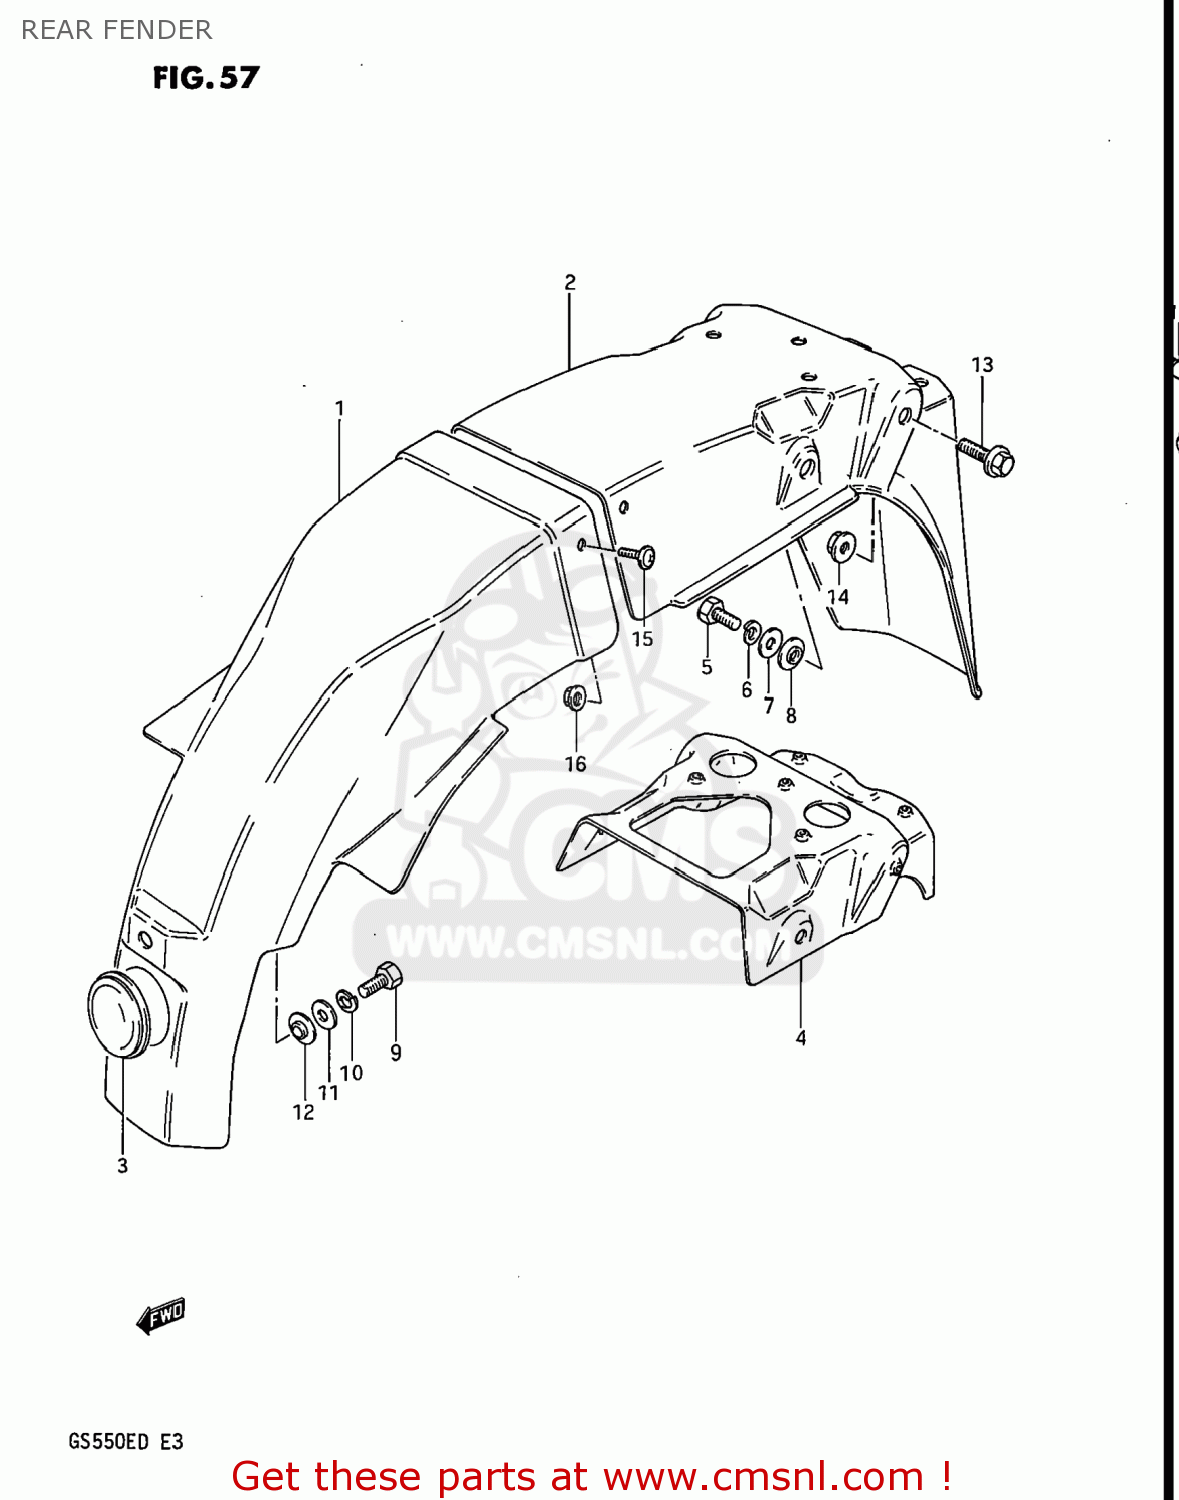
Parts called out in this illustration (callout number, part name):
1	BODY,REAR FENDER,FRONT
2	BODY,RR FENDER RR
3	GROMMET,REAR FENDER,FRONT
4	REINFORCEMENT,REAR
5	BOLT
6	LOCK WASHER
7	WASHER
8	WASHER
9	BOLT, UPPER
10	LOCK WASHER
11	WASHER 6MM
12	WASHER
13	BOLT
14	NUT
15	SCREW
16	NUT
